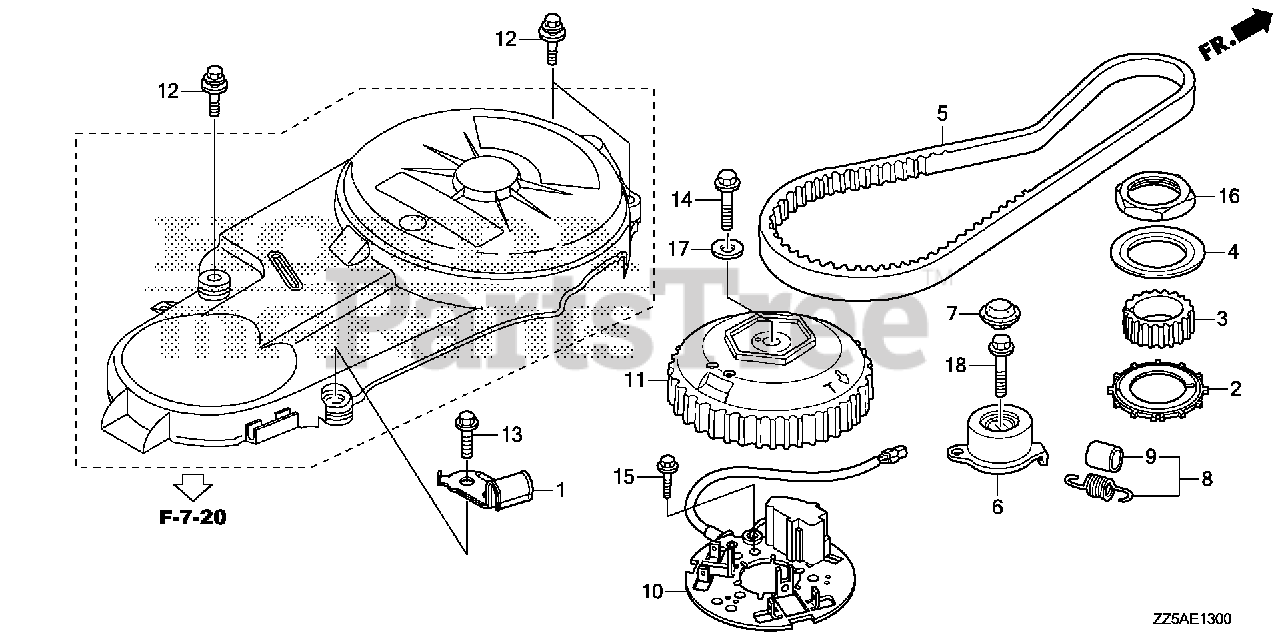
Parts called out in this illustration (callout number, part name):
1	CLAMP, TUBE
2	PLATE, TIMING BELT GUIDE
3	PULLEY, TIMING (22T)
4	PLATE, TIMING BELT GUIDE
5	BELT, TIMING
6	TENSIONER, TIMING BELT
7	CAP, TIMING BELT TENSIONER
8	SPRING, TIMING BELT ADJUSTING
9	BOOT, SPRING
10	COIL ASSY., PULSER
11	ROTOR, PULSER (44T)
12	BOLT-WASHER (6X25)
13	BOLT, FLANGE (6X25)
14	BOLT, FLANGE (10X32)
15	BOLT, FLANGE (6X12)
16	NUT, LOCK (48MM)
17	WASHER (10X28X5)
18	BOLT, FLANGE (10X38)
